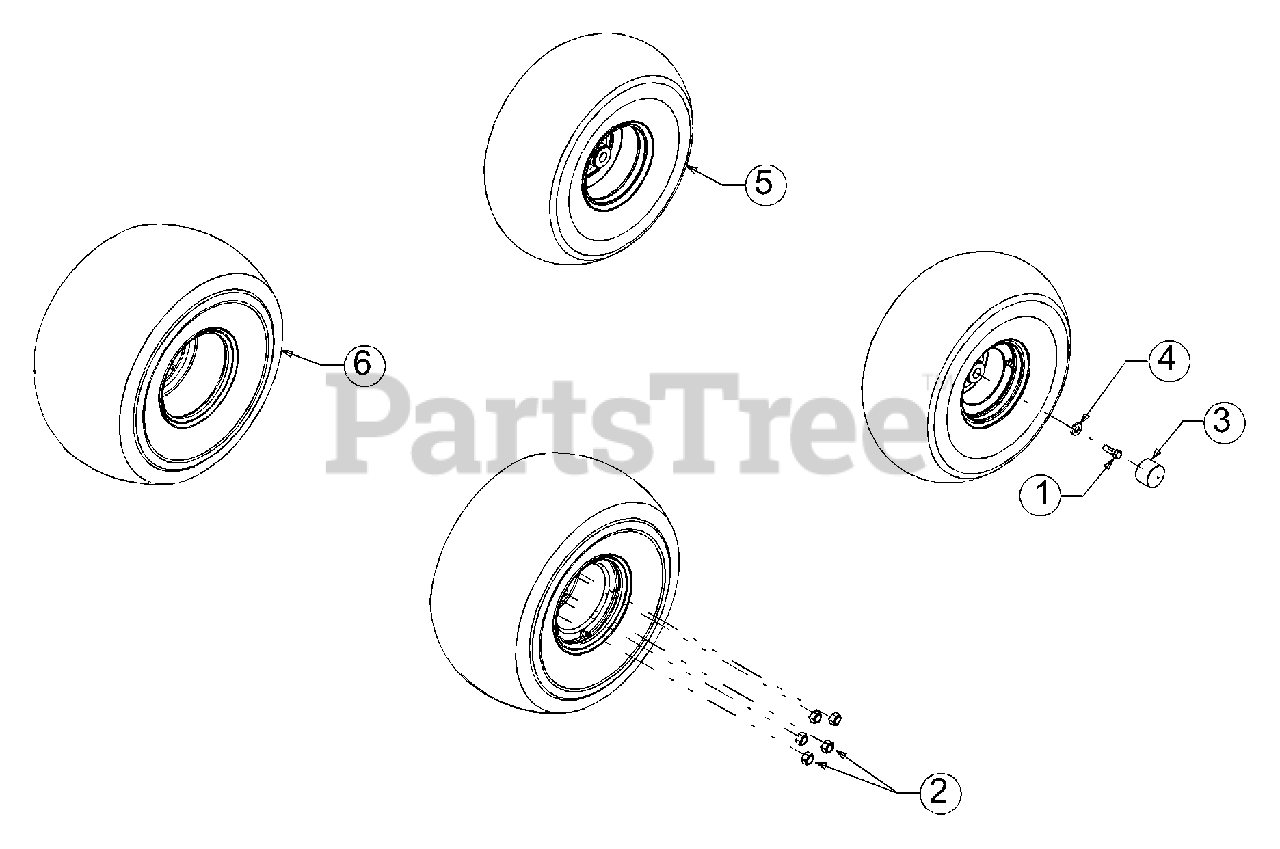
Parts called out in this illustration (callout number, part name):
1	Hex Screw, 1/2-13 x 1.5, Gr5
2	Nut Hex, 7/16-20
3	Dust Cover
4	Washer, Flat, .531 x 1.25 x .181
5	Wheel Assembly 22.5 x 10 x 8 (Turf)
5	Wheel Assembly 22 x 11 RH (AT)
5	Wheel Assembly 22 x 11 LH (AT)
6	Wheel Assembly 25 x 12 x 9 (Turf)
6	Wheel Assembly 25 x 11 x 10 RH (AT)
6	Wheel Assembly 25 x 11 x 10 LH (AT)
